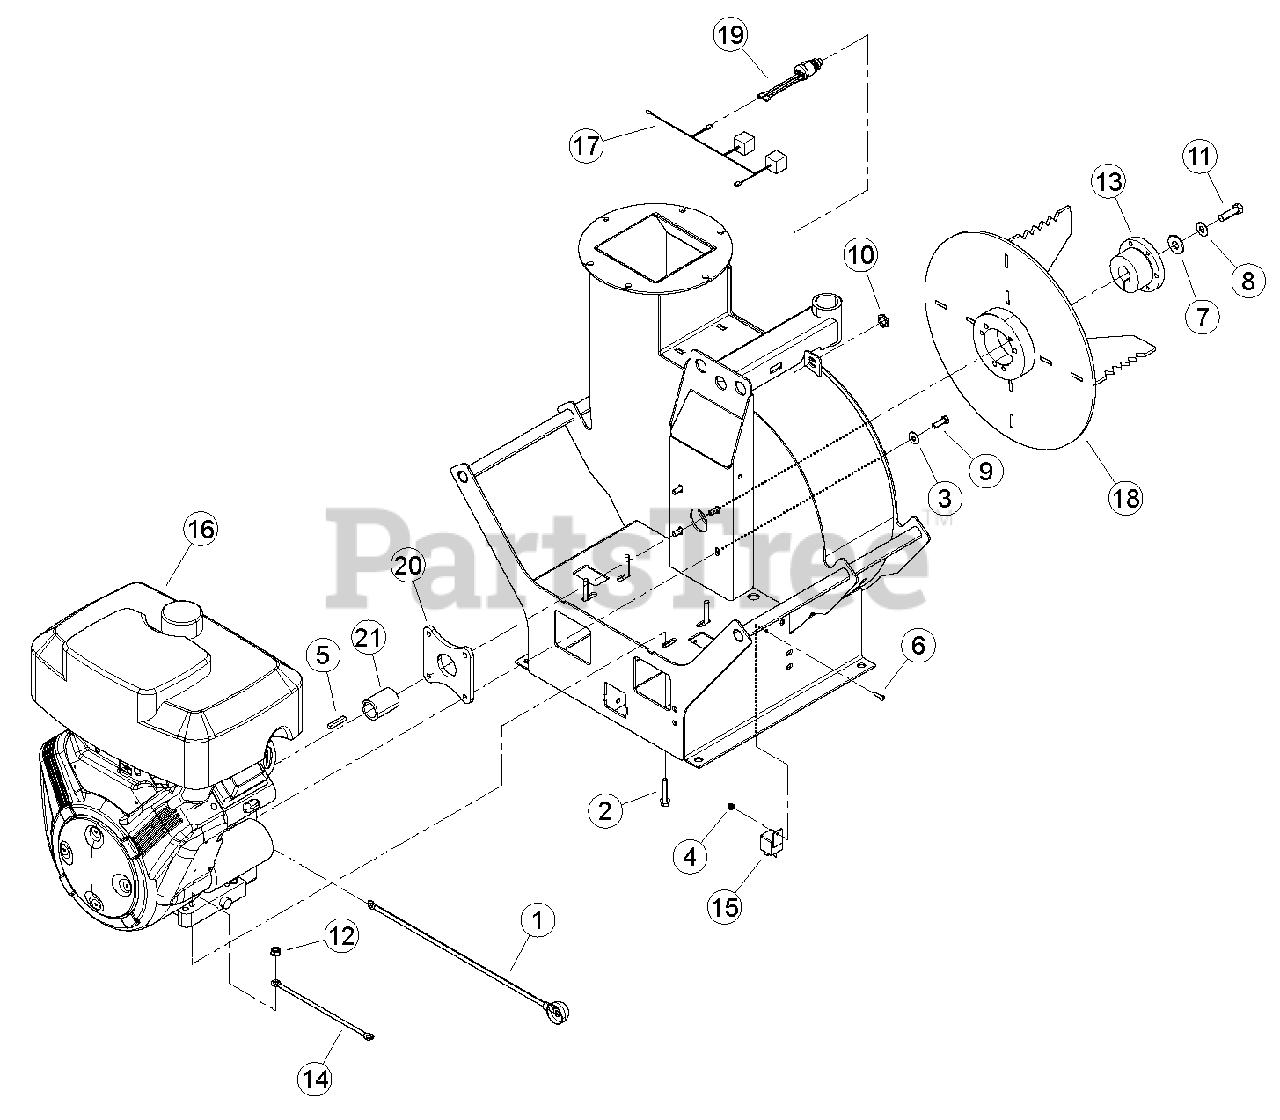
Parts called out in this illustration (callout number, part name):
1	CABLE, 18" POS (R/R WITH BOOT)
2	BOLT, 5/16 X 1-3/4 FLANGE NC
3	WASHER, 5/16 FLAT
4	NUT, 10/24 NYLOCK TYPE NM ZP
5	KEY, 1/4 SQ X 1-1/2 LG PLAIN
6	SCREW, MCH #10-24 X 3/4" PAN HD PH ZP
7	WASHER, 1/2 USS GR8 ZP
8	WASHER, 3/8 USS GR8 ZP
9	BOLT, 5/16-24 X 1" HHCS GR5 ZP
10	NUT, 5/8-32 JAM
11	BOLT, 7/16 X 1-1/2 NF GR5 HEX ZP
12	NUT, 5/16-18 NYLOCK-FLANGE
13	BUSHING SK 1-1/8"
14	CABLE, 9" NEG (R/R)
15	RELAY, 12V SPDT W/ FLANGE
16	ENGINE, BRIGGS V-TWIN 570CC ELECTRIC START (FOR SERVICE SEE ENGINE OWNER'S MANUAL OR YOUR NEAREST BRIGGS & STRATTON INDUSTRIAL ENGINE DEALER)
17	HARNESS, BRIGGS ENGINE KILL SWITCH
18	WELDMENT, FAN "BEAR CLAW"
19	ASSEMBLY, SEALED SWITCH
20	PLATE, ENGINE SPACER
21	SPACER, 1-1/2" OD X 3/16" WA
